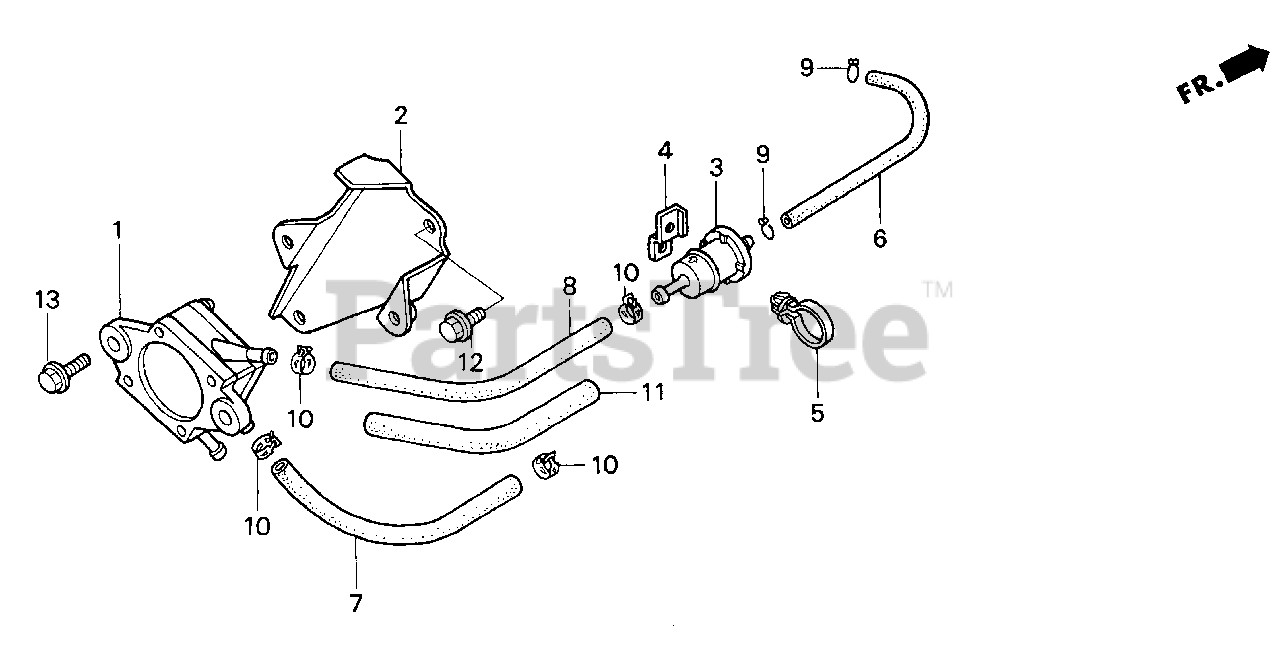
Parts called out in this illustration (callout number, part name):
1	PUMP ASSY., FUEL
2	STAY, FUEL PUMP
3	FILTER, FUEL
4	BASE, CLIP
5	CLIP, WIRE HARNESS
6	BULK HOSE, FUEL (4.5X3000) (4.5X110)
7	BULK HOSE, FUEL (5.5X8000) (5.5X195)
8	BULK HOSE, FUEL (5.5X8000) (5.5X215)
9	CLIP, TUBE (B8)
10	CLIP, TUBE (10.5MM)
11	BULK HOSE, VINYL (11X13X3000) (11X13X160)
12	BOLT, FLANGE (6X8)
13	BOLT, FLANGE (6X14)
